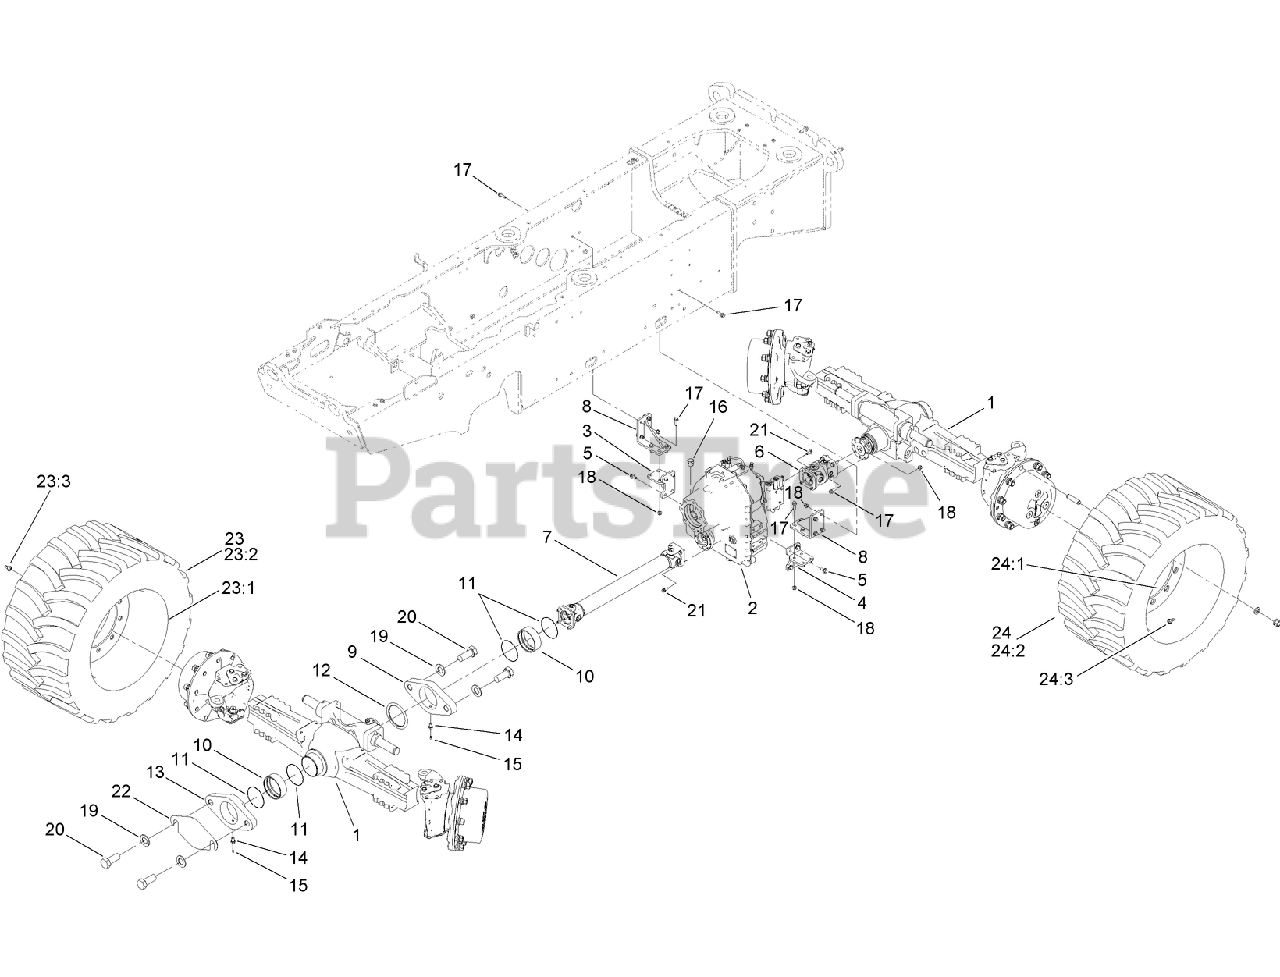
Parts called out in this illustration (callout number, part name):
1	AXLE ASM
2	TRANSMISSION-2 SPEED, POWERSHIFT
3	MOUNT-TRANSMISSION, RH
4	MOUNT-TRANSMISSION, LH
5	SCREW-HHF
6	CONSTANT VELOCITY JOINT ASM
7	FRONT AXLE DRIVE SHAFT ASM
8	MOUNT-TRANSMISSION
9	HOUSING-MOUNT, TRUNION
10	BUSHING-PIVOT
12	WASHER-THRUST
13	HOUSING-MOUNT, TRUNION
14	ADAPTER-LOCATING
15	FITTING-GREASE
16	PLUG-HYD
17	SCREW-HHF
18	NUT-LOCK, NI
21	SCREW-HHF
22	SHIM-MOUNT, AXLE
23	RH TIRE ASM
23:2	TIRE-TRENCHER
23:3	STEM-VALVE
24	LH TIRE ASM
24:2	TIRE-TRENCHER
24:3	STEM-VALVE
